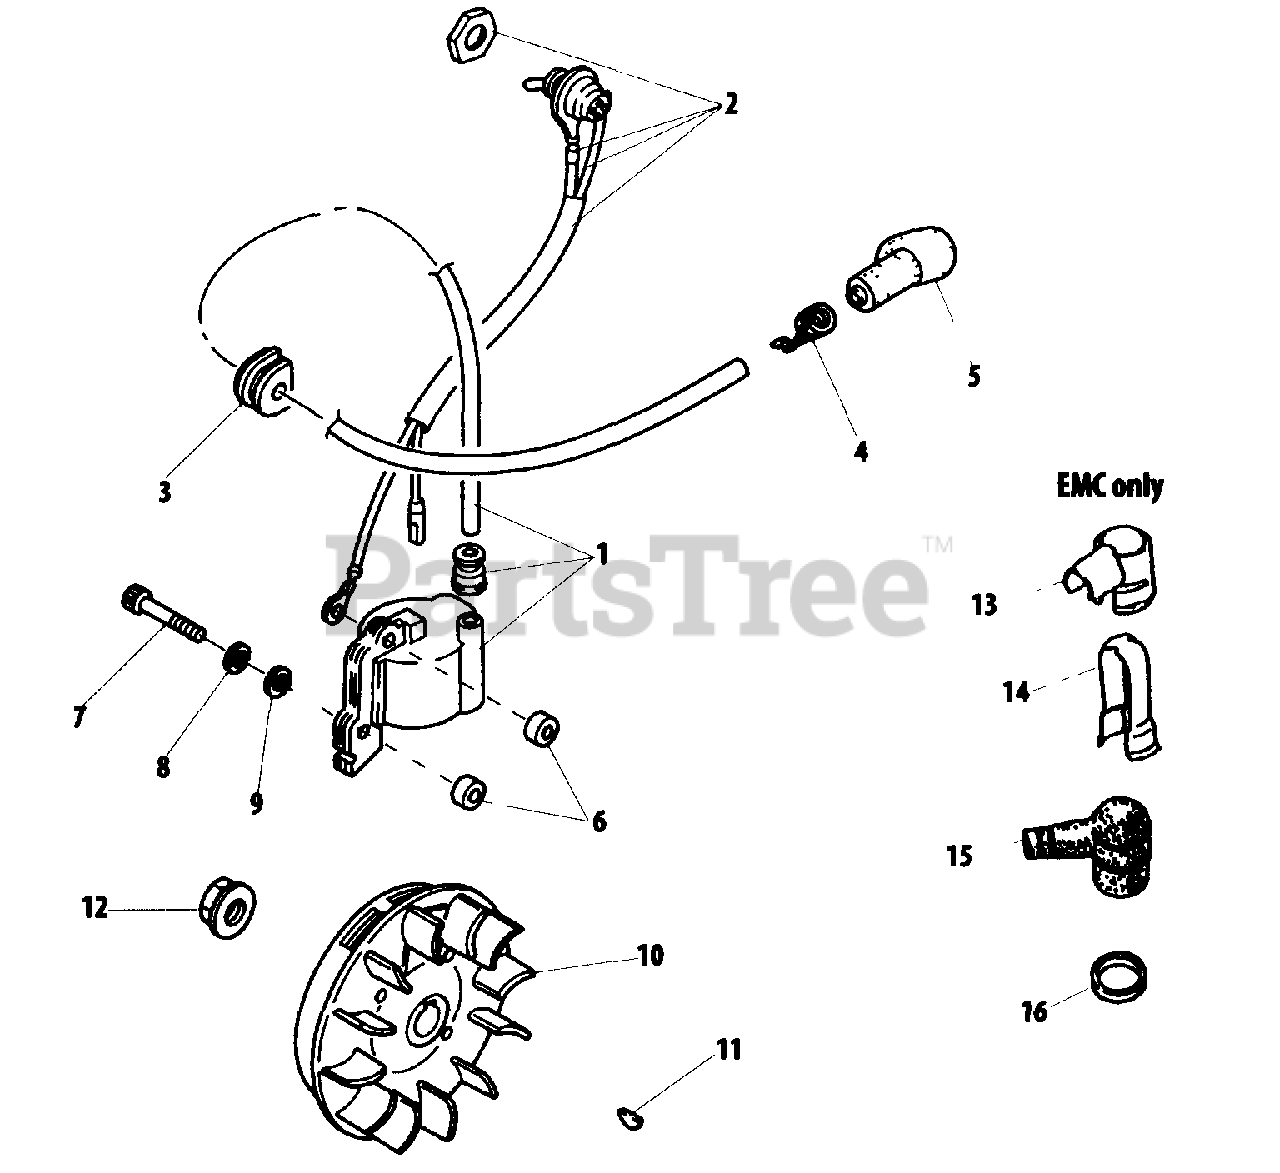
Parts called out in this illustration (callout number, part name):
1	COIL, IGNITION
2	SWITCH, ON-OFF
3	GROMMET
4	TERMINAL, SPARK PLUG
5	CAP, SPARK PLUG
6	INSULATOR 4.2×11×6
7	BOLT
8	WASHER, SPRING 4 MM
9	WASHER 4.3×9.6×0.8
10	FLYWHEEL
11	KEY, WOODRUFF 3×10
12	NUT M8
13	COVER, CAP
14	SHIELD
15	CAP, SPARK PLUG
16	SEAL, SPARK PLUG
